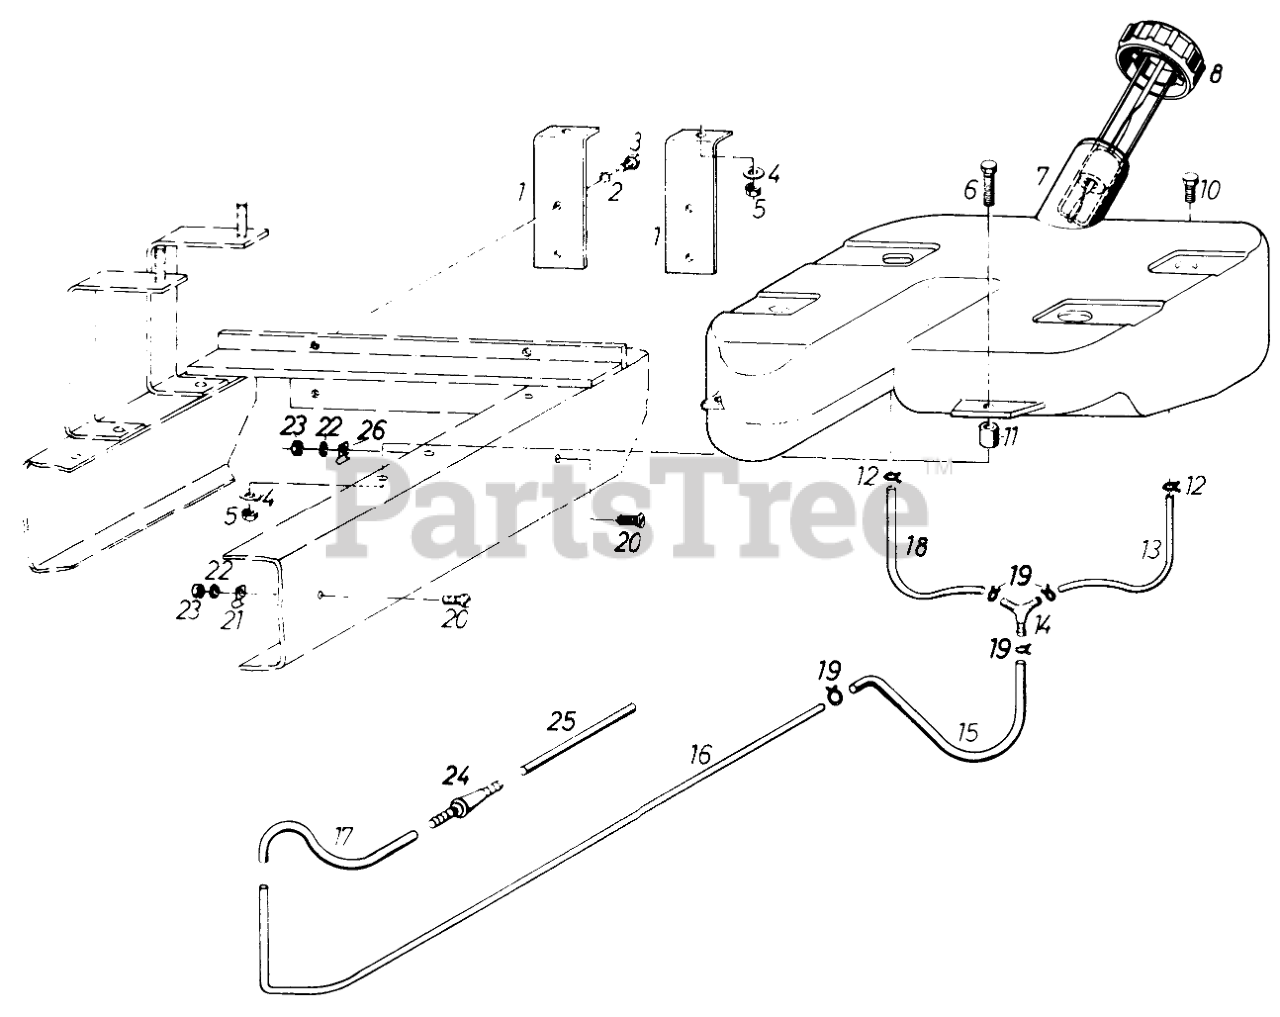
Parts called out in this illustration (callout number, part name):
1	Bracket
2	Lockwasher
4	Washer
7	Tank
8	CAP-FUEL TANK
11	Shim
12	Clamp
13	Fuel Tube
14	Distributor
15	Fuel Pipe
16	Fuel Pipe
17	Fuel Pipe
18	Fuel Pipe
20	Screw
22	Washer
24	FILTER
25	Fuel Pipe
26	Clamp
